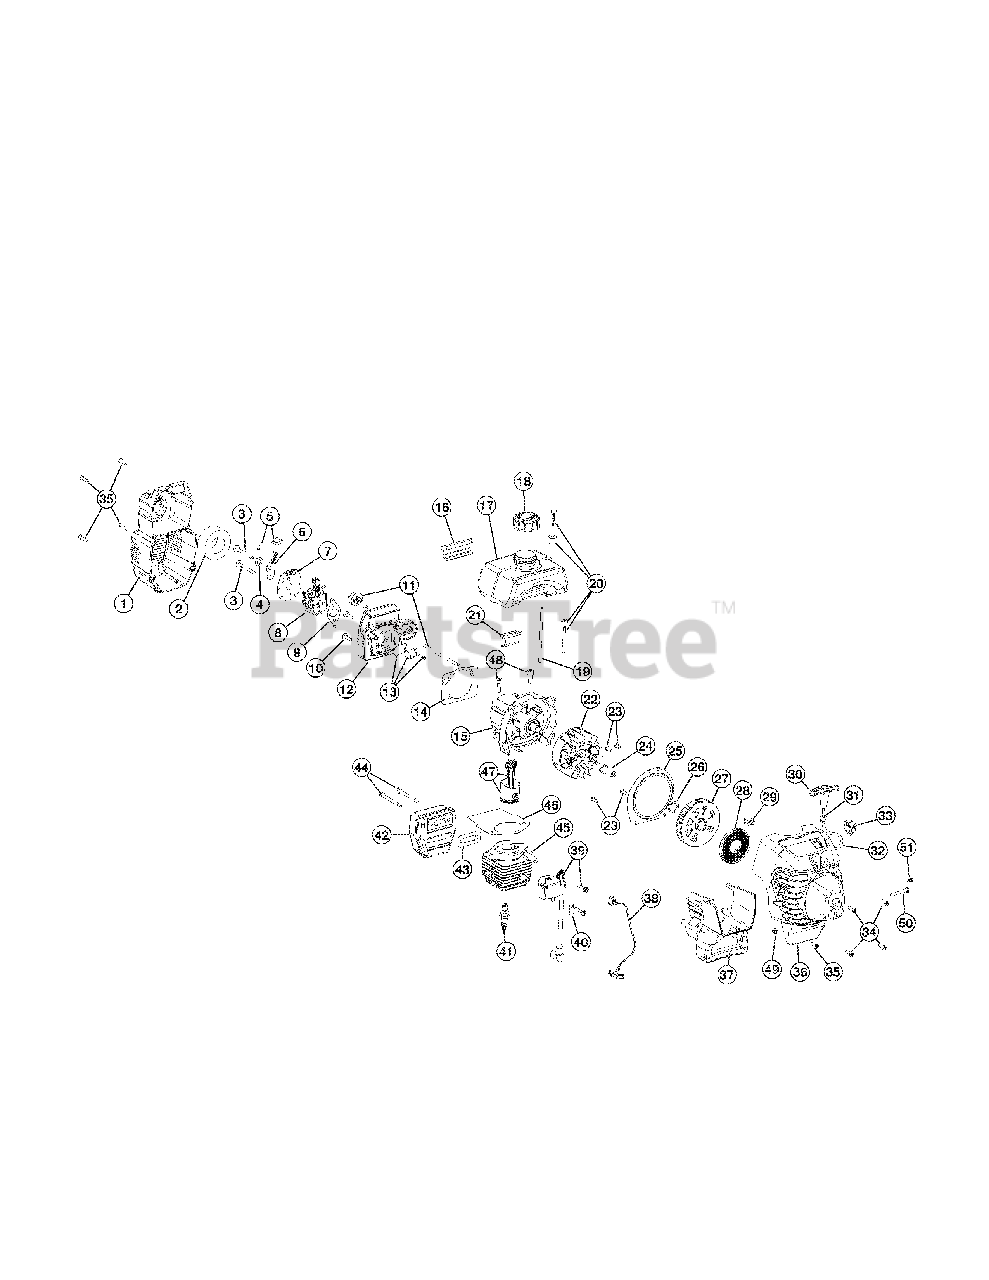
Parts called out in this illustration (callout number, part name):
1	Air Cleaner Cover Assembly (includes 2 & 35)
2	Air Cleaner Filter
3	Carburetor Mounting Screws
4	Wavey Washer
5	Choke Knob & Screw
6	Choke Lever Assembly (includes 5)
7	Choke Lever & Plate (includes 6)
8	Carburetor Assembly (includes 9 & 20)
9	Carburetor Gasket
10	Carb Mount Screw
11	Primer and Hose Assembly
12	Carburetor Mount Assembly (includes 10, 13 & 14)
13	Reed Assembly
14	Carburetor Mount Gasket
15	Crankcase Service Assembly (includes 10 & 23)
16	Rear Mounting Pad
17	Fuel Tank Assembly (includes 18 & 20)
18	Fuel Cap Assembly
19	Fuel Return Line
20	Fuel Line Assembly
21	Front Mounting Pad
22	Flywheel Assembly
23	Plate Screw
24	Square Nut Drive
25	Pressure Plate (includes 23 & 29)
26	Palnut
27	Recoil Pulley Assembly
28	Recoil Spring
29	Eyelet Retainer
30	Pull Handle
31	Rope Guide
33	Switch Assembly (includes 38)
34	Housing Screw
35	Cover Screw
36	Starter Housing Assembly (includes 23, 25-32, 34 & 34)
37	Shroud Extension and Stand (includes 35)
38	Wire Lead
39	Module Assembly
40	Ground Tab
41	Spark Plug
42	Muffler Assembly (includes 43 & 44)
43	Exhaust Gasket
44	Muffler Mounting Bolt Assembly
45	Cylinder Assembly (includes 47 & 48)
46	Piston & Rod Assembly
47	Cylinder Gasket
48	Cylinder Bolt
49	Clamping Nut
50	Clamping Screw
51	Anti-Rotation Screw
